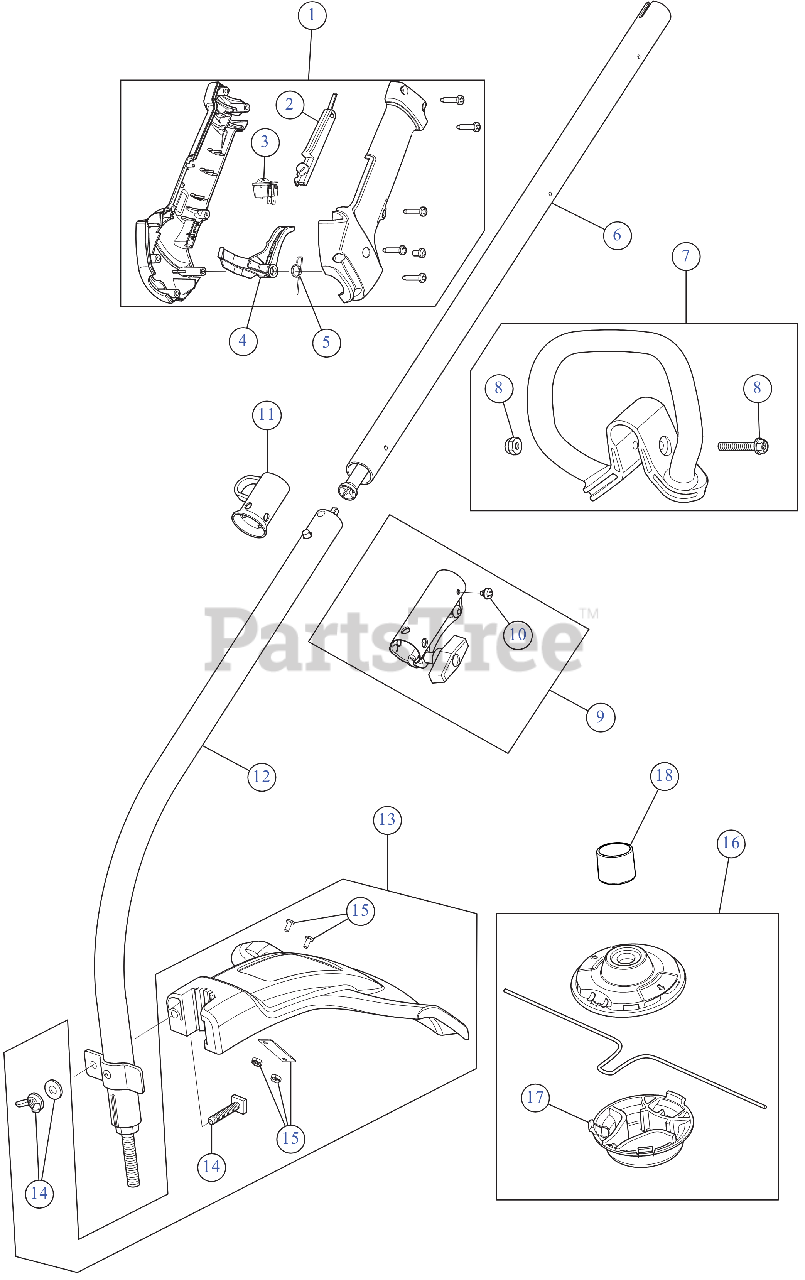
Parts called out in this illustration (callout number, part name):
1	THROTTLE GRIP ASSEMBLY
2	LOCK OUT LEVER
3	SW, MOMENTARY ON/O
4	THROTTLE TRIGGER
5	SPRING TRIG
6	BOOM ASSEMBLY UPR
7	D-HANDLE
8	BOLT 1/4-20X1 1/2
9	SPLIT BOOM COUPLER KIT
10	SCREW, 10-32X.250 TA
12	BOOM ASSEMBLY LOWER
13	GUARD ASSEMBLY
14	BLADE GUARD MOUNTING HARDWARE
15	ASSEMBLY, BLADE
16	HEAD ASSEMBLY FIXED LIN
17	HEAD FIXED LINE BT
18	WEED GUARD
